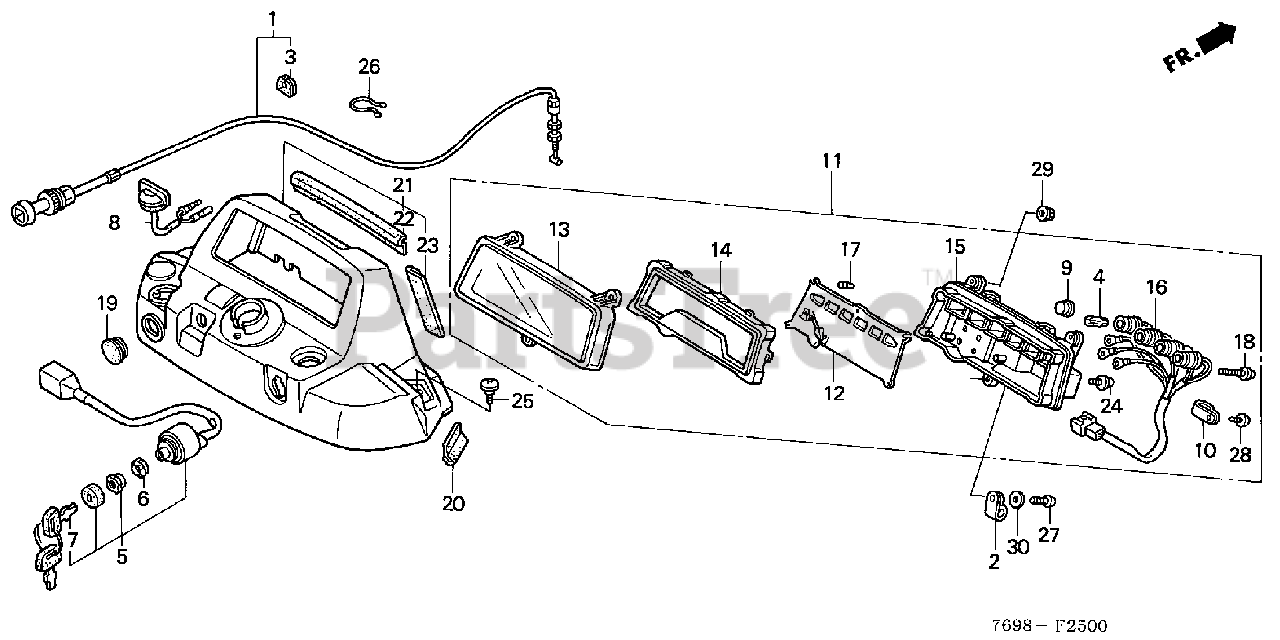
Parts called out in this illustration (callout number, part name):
1	CABLE, CHOKE
2	CLAMP, IGNITION WIRE
3	GROMMET, WIRE
4	BULB, WEDGE BASE (12V 3.4W)
4	BULB (12V3.4W) (158)
4	BULB (12V3.4W2CP) (158) (NS)
5	SWITCH ASSY., COMBINATION
6	BASE, COMBINATION SWITCH
7	KEY ASSY., COMBINATION SWITCH
8	SWITCH ASSY., ENGINE STOP
11	INDICATOR ASSY.
12	METER, FUEL
12	METER, FUEL & HOUR
14	PLATE, REFLECTING
17	RUBBER, CUSHION
18	SCREW-WASHER (3X22)
19	GROMMET, CARRYING HANDLE
20	SEAL D, COLUMN COVER (45MM)
21	PANEL, INSTRUMENT *NH105* (MAT BLACK)
22	SEAL, INSTRUMENT
23	SEAL, INSTRUMENT SIDE
24	SCREW-WASHER (3X8)
25	SCREW, METER VISOR SETTING
26	CLIP, PURSE LOCK
27	SCREW, PAN (5X25)
28	SCREW, TAPPING (4X16)
29	NUT, FLANGE (5MM)
30	WASHER, PLAIN (5MM)
